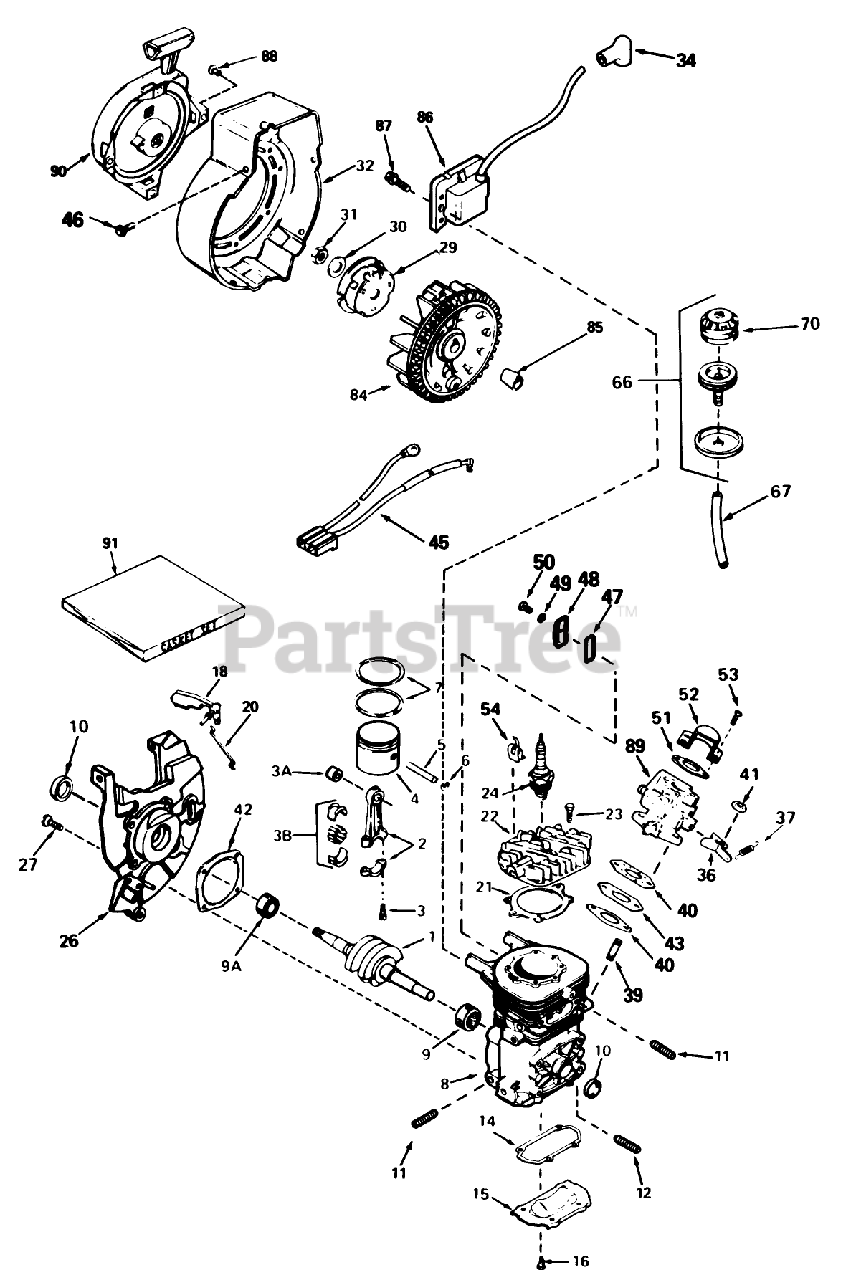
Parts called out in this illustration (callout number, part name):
1	Crankshaft
2	Rod Assy.-Connecting (Incl. Ref. #3, 3A 3B)
3	Bolt-Rod, Connecting
3A	Bearing-Cartridge
3B	Needle Bearing and Liner Set (37 Needles)
4	Piston
5	Pin-Piston
6	Ring-Retaning
7	Ring Set
8	Block Assy.-Cylinder (Order short block if replacement is required.)
9	Bearing-Cartridge
9A	Bearing-Ball
10	Seal-Oil
14	Cover
15	Plate-Cover
16	Screw (T-25, 10-24 x 1/2)
18	Vane Assy., Air
20	Link-Governor
21	Gasket, Head
22	Head-Cylinder
23	Screw (T-30, 1/4-20 x 3/4)
24	Spark Plug-Resistor (R C J 8Y)
26	Base Assy.-Blower Housing (Incl. Ref. #10)
27	Screw (1/4-20x19/32)
29	Cup-Starter
30	Washer-Belleville
31	Nut-Flywheel
32	Housing-Blower
34	Cover-Spark Plug
36	Lever-Adjusting, Rpm
37	Spring-Governor
40	Gasket-Carburetor
41	Locknut
42	Gasket, Shroud Base
43	Spacer
45	Harness-Wire
46	Screw-Hex, Hd.
47	Gasket-Cover
48	Comp. Release Cover
49	Washer
50	Screw (T-25, 10-24 x 1/2)
51	Gasket
52	Baffle-Carburetor
53	Screw
66	Primer Assy.
67	Line-Primer
70	Bulb-Primer
84	Flywheel
85	Blade (20 inch)
86	Solid State
87	Screw
88	Rivet-Pop (3/16" Dia.)(Can be purchased locally)
89	Carburetor (Incl. Ref. #40)
90	Starter-Rewind
91	Gasket Set
